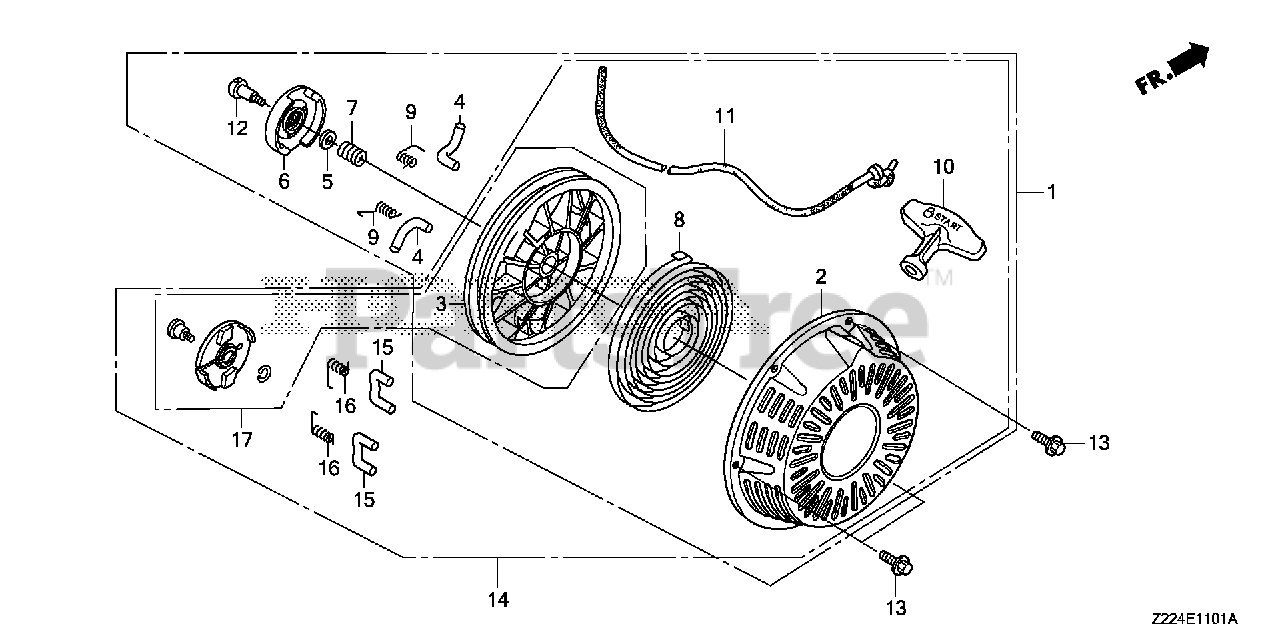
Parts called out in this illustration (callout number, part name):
1	STARTER ASSY., RECOIL *NH1* (BLACK)
2	CASE, RECOIL STARTER *NH1* (BLACK)
3	REEL, RECOIL STARTER
4	RATCHET, STARTER
5	PLATE, FRICTION
6	GUIDE, RATCHET
8	SPRING, RECOIL STARTER
9	SPRING, RETURN
10	GRIP, STARTER
11	ROPE, RECOIL STARTER
12	SCREW, SETTING
13	BOLT, FLANGE (6X10)
14	STARTER ASSY., RECOIL *NH1* (BLACK)
15	RATCHET, STARTER
16	SPRING, RETURN
17	STARTER SET, RECOIL
